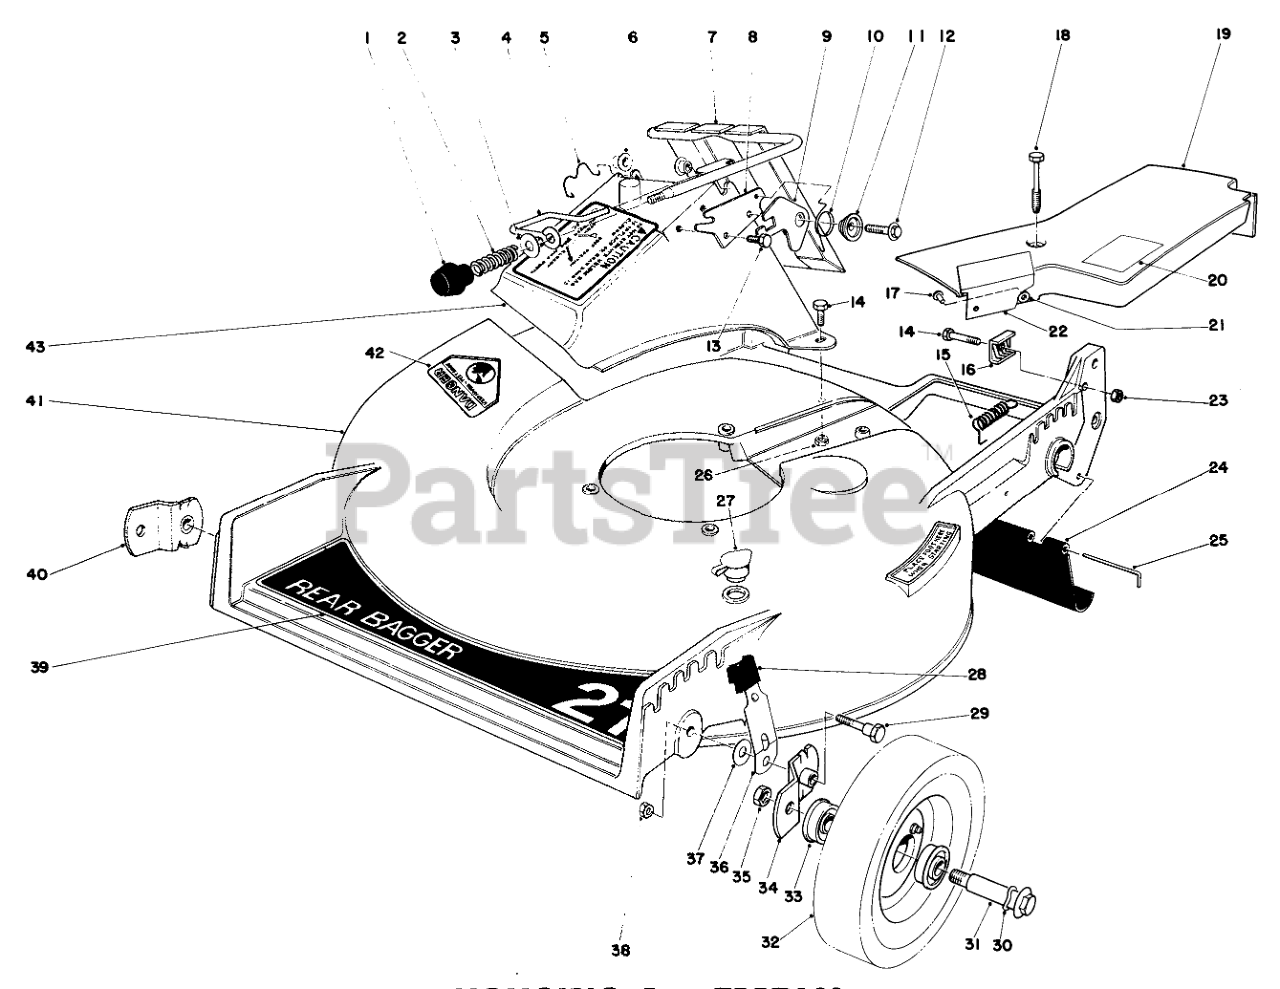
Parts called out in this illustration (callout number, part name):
2	COMPRESSION SPRING
3	WASHER
4	DOOR LATCH
5	DOOR RETAINER
6	BUSHING-NYLON
7	DOOR & HANDLE WA
8	DOOR LATCH PLATE
9	Latch Safety
10	TORSION SPRING
11	Latch Spacer
12	Screw
13	SCREW-HWH
14	SCREW-HH
15	IDLER SPRING
16	CLAMP-CABLE
17	RIVET-HEAD, FLAT
18	SCREW-HHFTF
19	Belt Cover (Incl. Ref. #17 & 21-22)
20	Sticker Grease
21	WASHER-FLAT
22	HEAT SHIELD
23	NUT-JAM
24	SHIELD - TRAILING
25	Rod Shield
26	NUT-LOCK, NI
27	WASHOUT PLUG
28	KNOB-ARM
29	PIVOT SCREW
30	SPRING WASHER
32	Wheel & Tire Assembly (Incl. Ref. #33)
33	BEARING-BALL
34	PIVOT ARM ASM A
35	Nut
36	SPRING ARM ASM (R&S)
37	WASHER-PIVOT
38	Nut
39	Decal-Deck
40	PIVOT ARM ASM B
41	Housing
42	DECAL-DANGER
43	DISCHARGE CHUTE B
